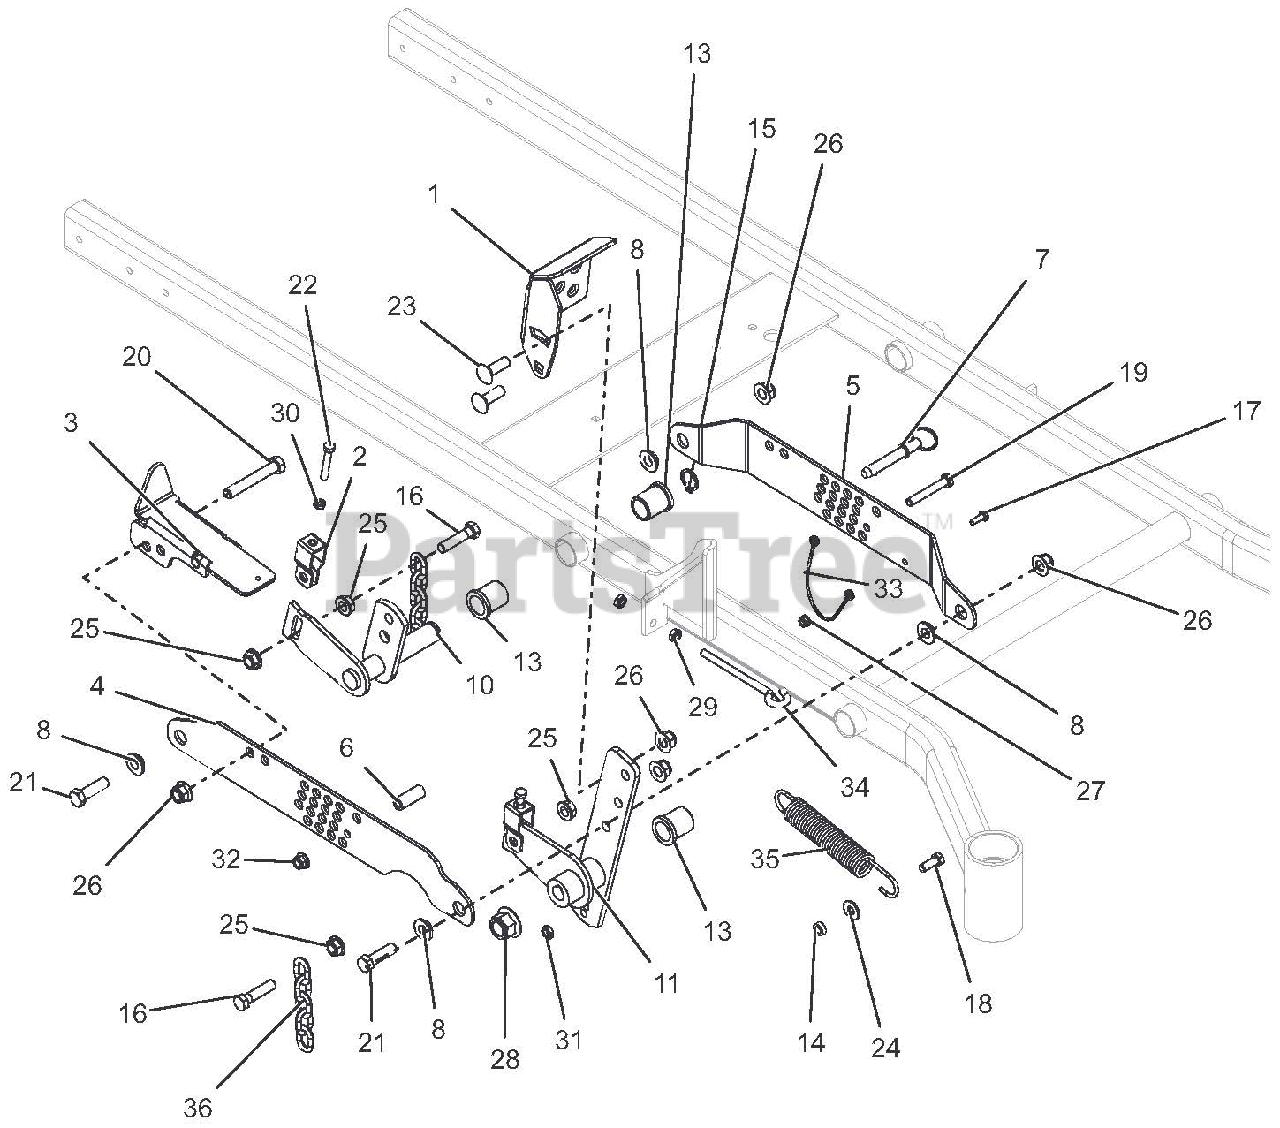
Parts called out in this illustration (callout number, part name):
1	PEDAL, ADJUSTABLE FOOT LIFT
2	BRKT, DECK LEVELING
3	WLDMT, MECHANICAL LOCK-UP - BLACK
4	BRKT, RH OUTBLOARD LIFT/CUT HEIGHT-BLACK
5	BRKT, RH INBOARD LIFT/CUT HEIGHT - BLACK
6	SPACER, .375 X .625 X 1.52
7	PIN, .500 X 2.000 USABLE LG BALL
8	BSHG, FLANGE .515 X .750 X .31 X 1.12
10	WLDMT, REAR RH DECK LIFT
11	WLDMT, PT FRONT RH DECK LIFT ARM - BLACK
13	BSHG-FLG 1.00 X 1.25 X 1.5 X 1.5
14	BSHG, SLV .377X.624X.235
15	RG-RTNG-EXT 1.000 X .078
16	BLT, HEX M12-1.75X50 CLS8.8 YZ
17	BLT-HEX .25-20X.75 GR5 YWZC
18	BLT-HEX .38-16 X 1.00 GR5 YWZC
19	BLT-HEX .38-16 X 2.50 GR5 YWZC
20	BLT-HEX .50-13 X 3.25 GR5 YWZC
21	BLT-HEX .50-13 X 1.75 GR5 YWZC
22	BLT-HEX .31-18 X 2.00 FTH GR5 YWZC
23	BLT-RDHDSQNK .50-13 X 1.50 G5 YWZC
24	WSHR-FL-STL .438 X 1.00 X .083 YWZC
25	NUT, SPLK -FLG M12-1.75 YZ
26	NUT-LK-NYL-FLG .50-13 YWZC
27	NUT-LK-NYL-FLG .25-20 YWZC
28	NUT-LK-NYL-FLG .75-10 YWZC
29	NUT, JAM .375-16 YWZC
30	NUT, JAM .312-18 YWZC
31	@NUT-LK-CTR-JAM .375-16 YWZC
32	NUT-LK-NYL-FLG .38-16 YWZC
33	LANYARD, 12"
34	BOLT, EYE .38-16X6.00 .62 DIA
35	SPRG, TENSION .162 X 1.250 X 8.250
36	CHAIN, MOWER LIFT
